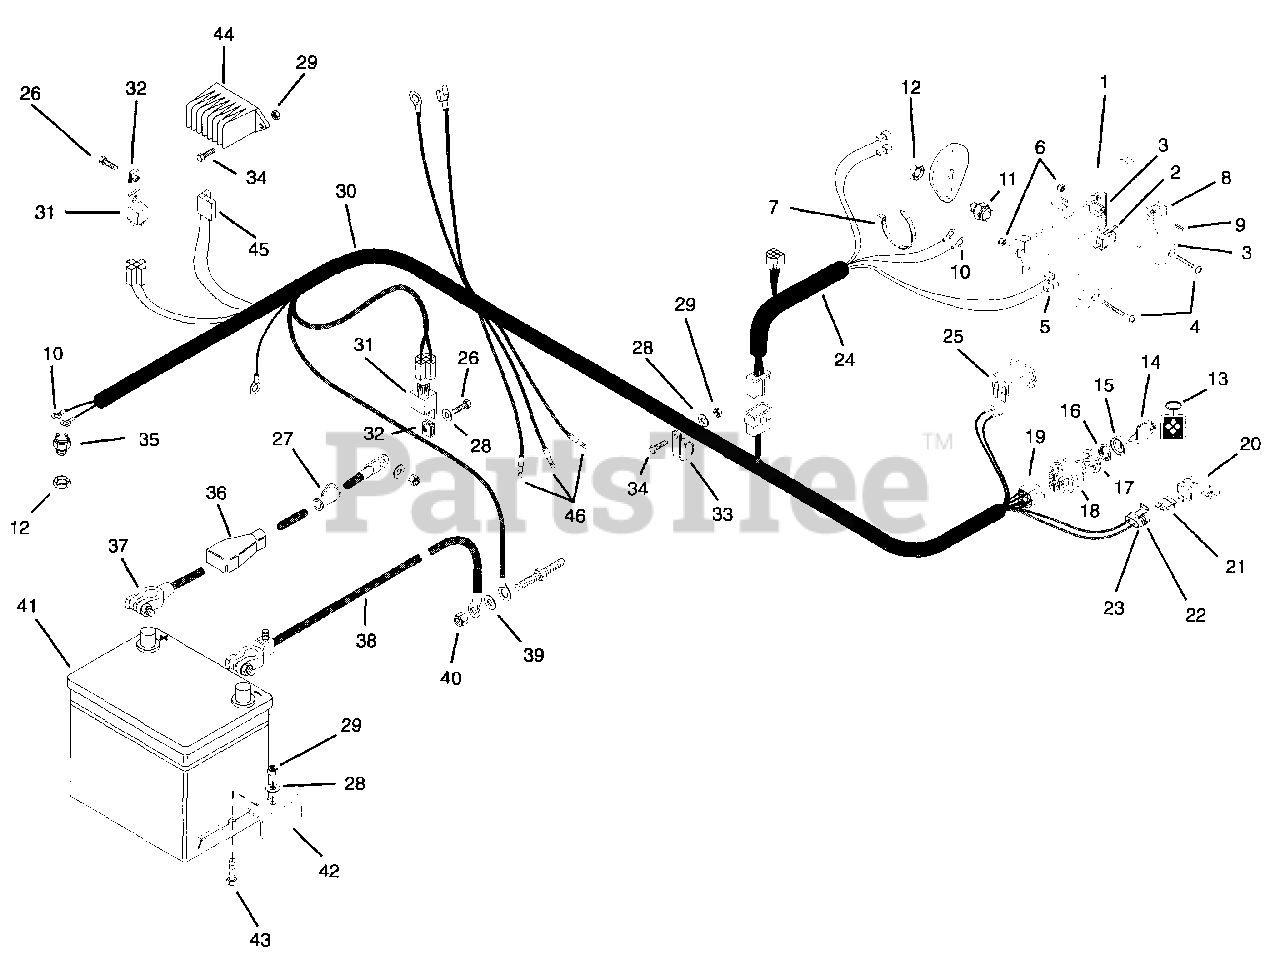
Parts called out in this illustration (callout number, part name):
1	Lever
2	Switch
3	Handle, Left Hand & Right Hand
4	Screw-Machine 10-24 x 1.50
5	Terminal, Female
6	Nut-Locking 10-24
7	Tie Wrap, Black
8	Holder, Switch
9	Pin-Roll .094 x .750
10	Terminal, Eyelet
11	Switch, Interlock Closed
12	Nut-Stamped .56-18
13	Key Chain
14	Ignition Switch Key
15	Cap-Ignition Switch
16	Nut-Panel .562-24
17	Washer-Lock Internal .563 x .040
18	Ignition Switch
19	Connector
20	Cover
21	Fuse, 7.5 Amp
22	Terminal For 10-12 Gauge Wire
23	Assembly, Connector Weather Tight
24	Harness, Wiring Handlebar
25	Hour meter
26	Bolt-Hex .25-20 x .63
27	Boot, Insulator (107,108,109)
28	Washer-Flat-Steel .281 x .620 x .065
29	Nut-Locking-Center .25-20
30	Harness, 10-HP Electric Kawasaki
30	Harness, 10, 12 & 16-HP Electric
30	Harness, 16-HP Electric
31	Relay
32	Nut-Speed .25-02
33	Clamp, Cushioned Steel
34	Bolt-Hex .25-20 x .75 Grade 5
35	Switch, Interlock Open
36	Cover, Battery Terminal
37	Cable, Positive Battery
37	Cable, Battery-To-Magneto
38	Cable, Negative Battery
39	Washer-Flat-Steel .406 x .812 x .065
40	Nut-Locking-Nylon .375-16 Grade 2
41	Battery, 12 Volt
42	Clamp
43	Bolt-Round Head Square Neck .25-20 x 1.75
44	Reg, Rectifier
45	Connector
46	Terminal, Male
